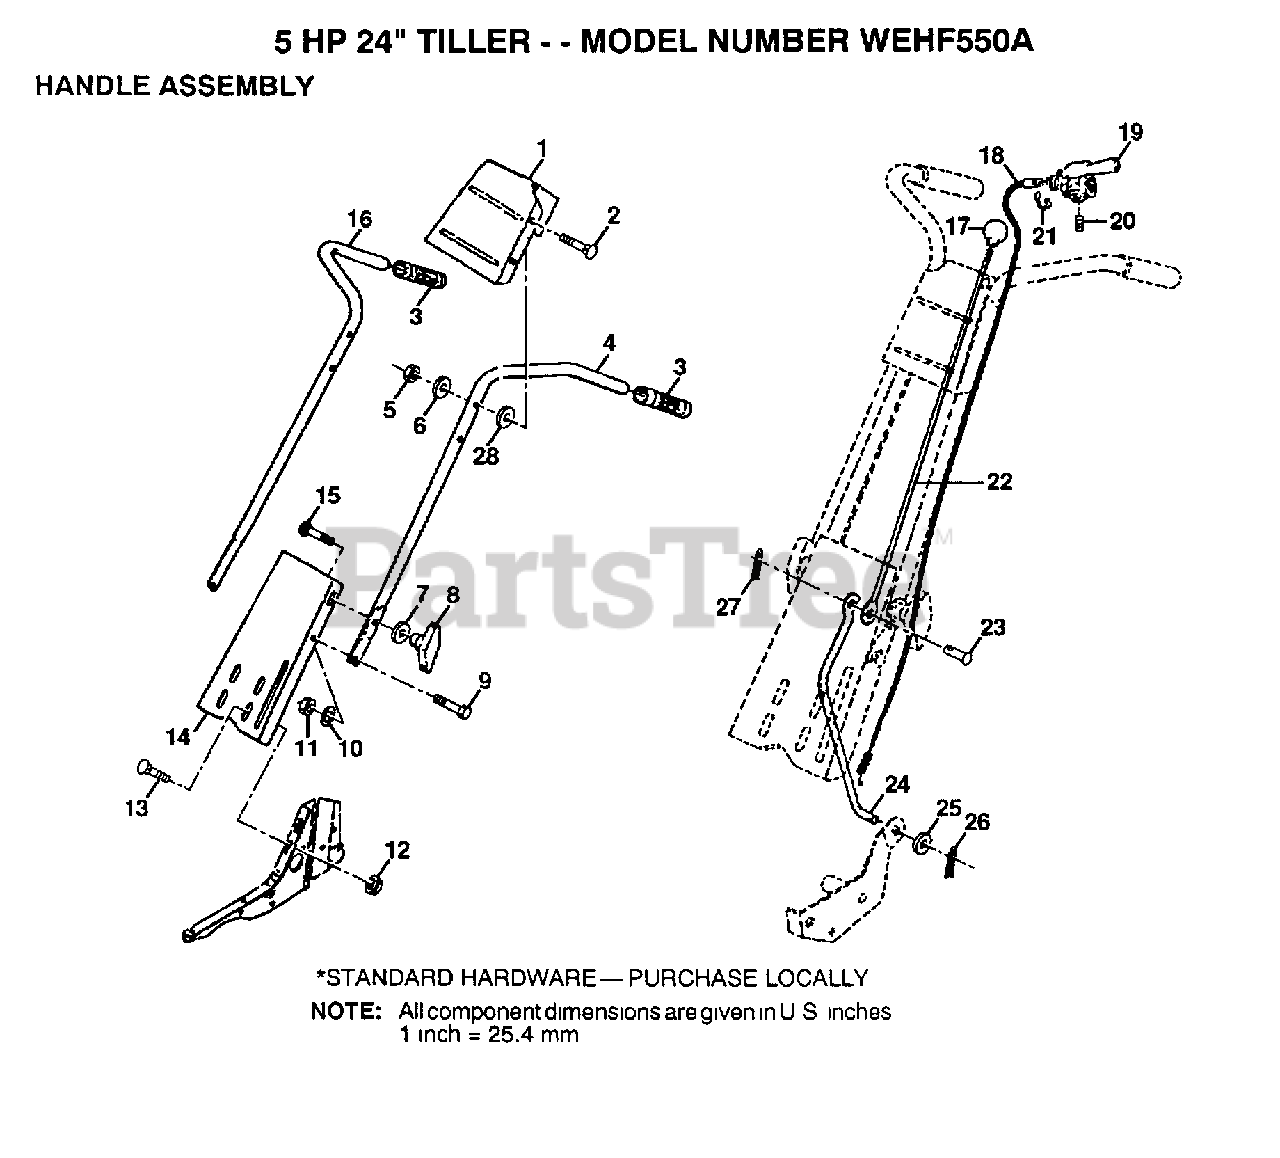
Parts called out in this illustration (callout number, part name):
1	HANDLE BRACKET
2	BOLT
6	WASHER
7	WASHER
8	KNOB HANDLE
10	LOCKWASHER
11	NUT.HEX.5/16-18
12	NUT
13	BOLT
15	BOLT
17	KNOB T(3/8 HOLE)
18	CABLE CLUTCH T
19	CONTROL LEVER TI
20	SCREW
21	E-RING
22	ROD REVERSE TI
23	RIVET.RD.HD.DRILL
24	ROD REVERSE LOWER
25	WASHER
26	COTTER PIN
28	WASHER
